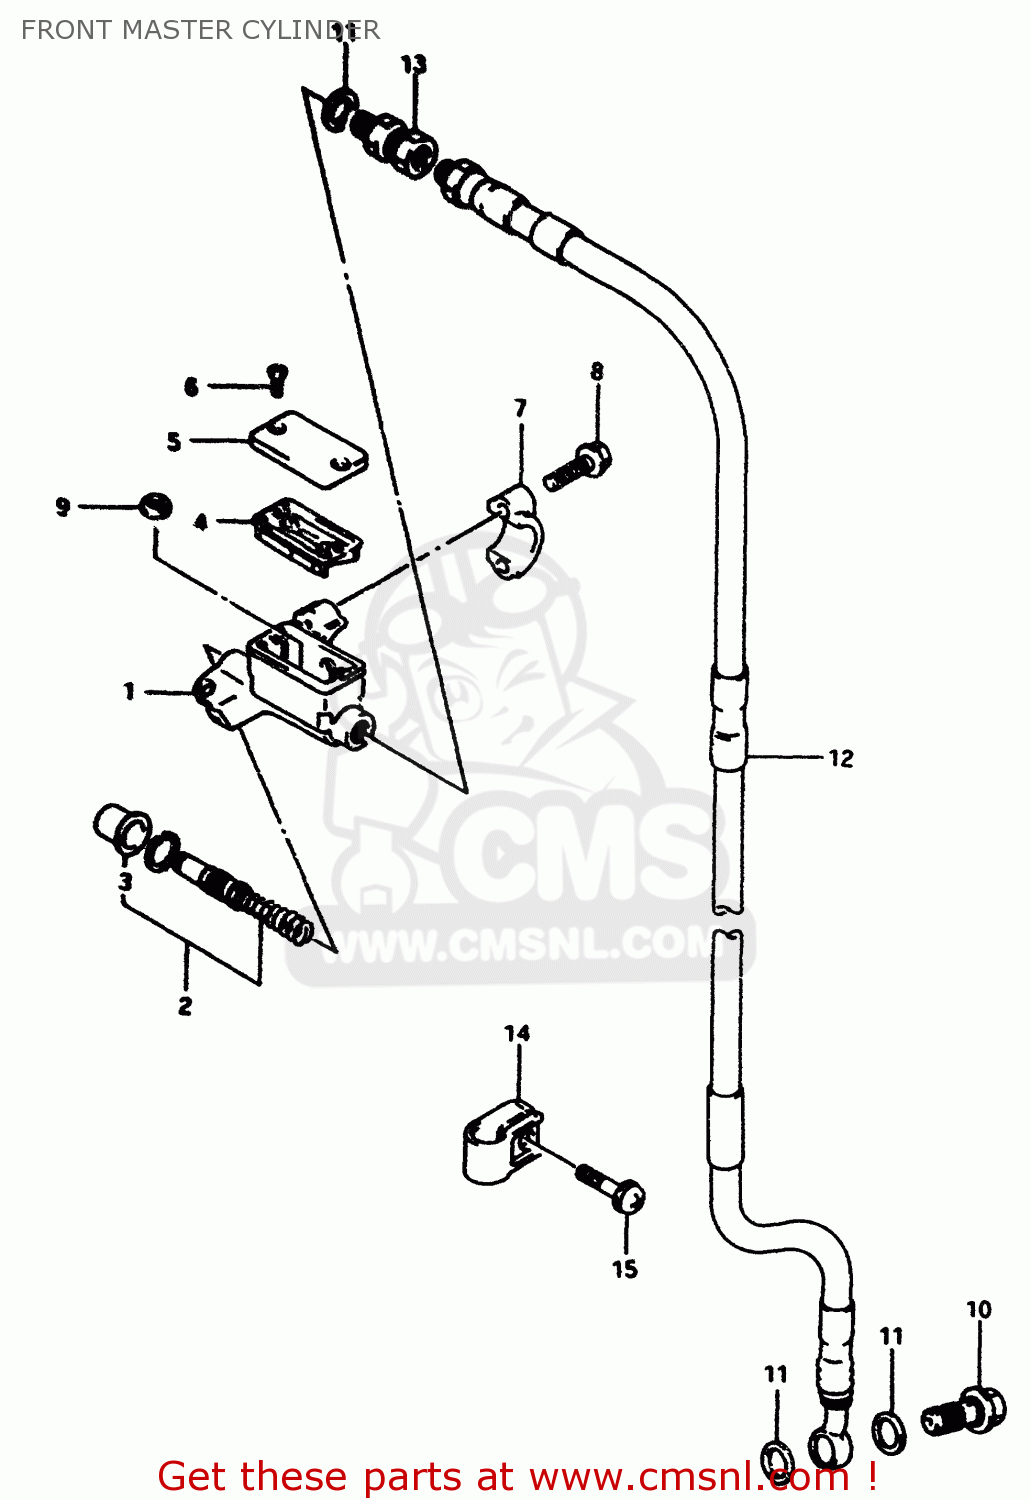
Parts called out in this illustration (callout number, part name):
1	CYLINDER ASSY,FR MASTER
2	PISTON & CUP SET
3	BOOT
4	DIAPHRAGM
5	CAP
6	SCREW
7	HOLDER
8	BOLT
9	SEPARATOR
10	BOLT UNION
11	WASHER(10X15X1.5)
12	HOSE,FR BRAKE
13	ADAPTOR,BRAKE HOSE
14	CLAMP,FR BRAKE
15	SCREW
